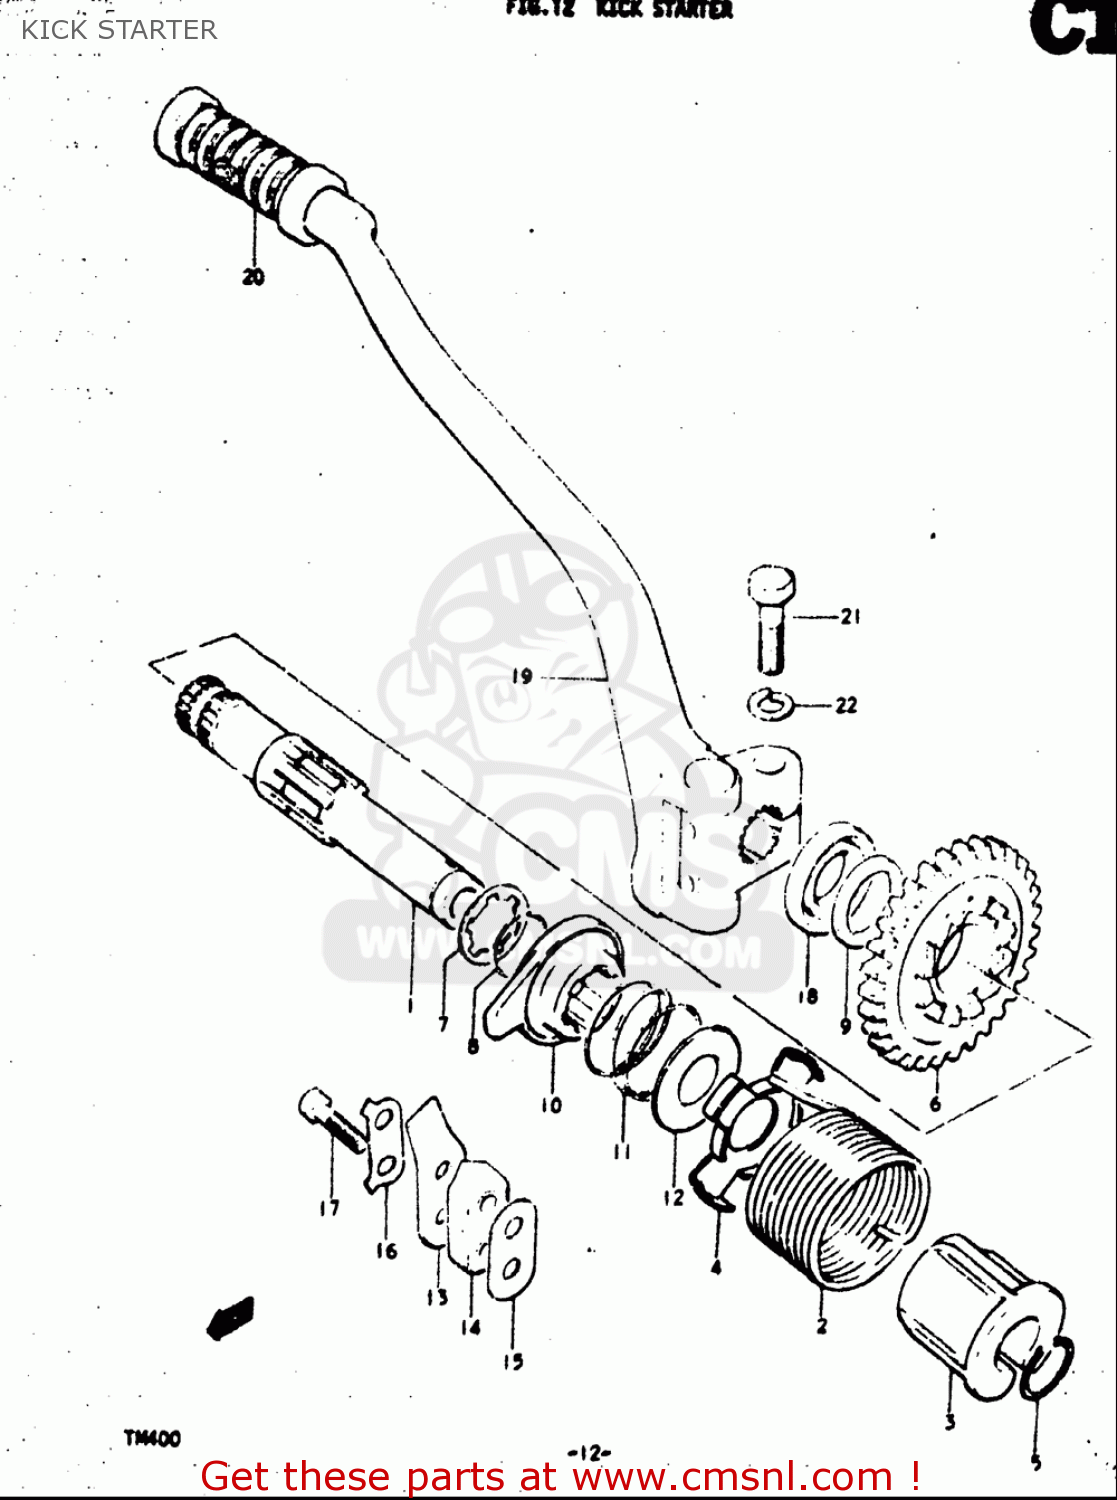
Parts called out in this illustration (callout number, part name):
2	SPRING
3	GUIDE,KICK SHAFT SPRING
4	HOLDER,KICK SHAFT SPRING
5	CIRCLIP
7	WASHER,LOCK
8	CIRCLIP
10	STARTER,KICK
11	SPRING
12	WASHER
17	BOLT
18	SEAL,OIL(20X37X7)
20	RUBBER,KICK STARTER PEDAL
21	BOLT
22	WASHER,LOCK
